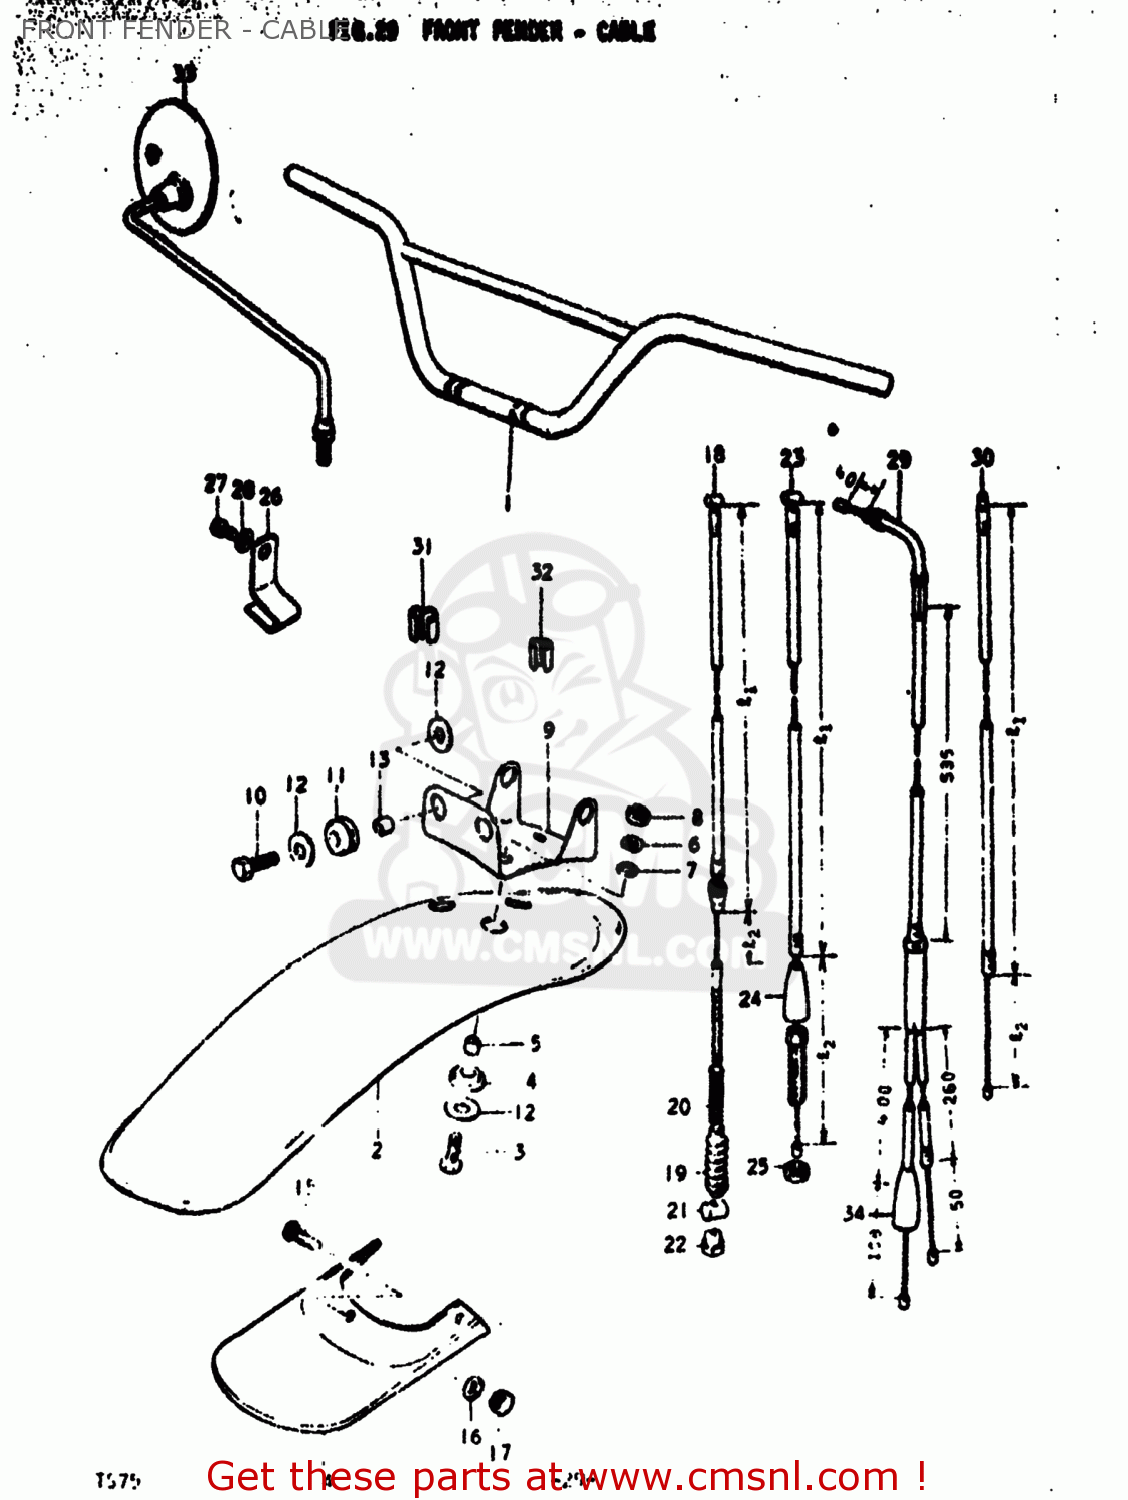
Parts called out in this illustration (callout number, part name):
1	HANDLEBAR
2	FENDER,FRONT
3	BOLT(6X18)
4	CUSHION
5	SPACER
6	LOCK WASHER
7	WASHER
8	NUT
9	BRACE,FRONT FENDER
10	BOLT
11	CUSHION
12	WASHER (6.5X20X1.2)
13	SPACER (7X9X7)
14	MUD FLAP,FRONT FENDER
15	SCREW
16	WASHER
17	NUT
18	CABLE ASSEMBLY,FRONT BRAKE
19	SEAL,DUST(7X16X75)
20	SPRING
21	PIN,10X19
22	NUT
23	CABLE ASSY,CLUTCH
24	SEAL,DUST(7X18X30)
25	NUT
26	CLAMP
27	BOLT
28	LOCK WASHER
29	CABLE ASSEMBLY,THROTTLE
30	CABLE COMP,STARTER
31	CLIP
32	CLIP
33	MIRROR ASSEMBLY,LEFT
34	SEAL,DUST(7X18X30)
